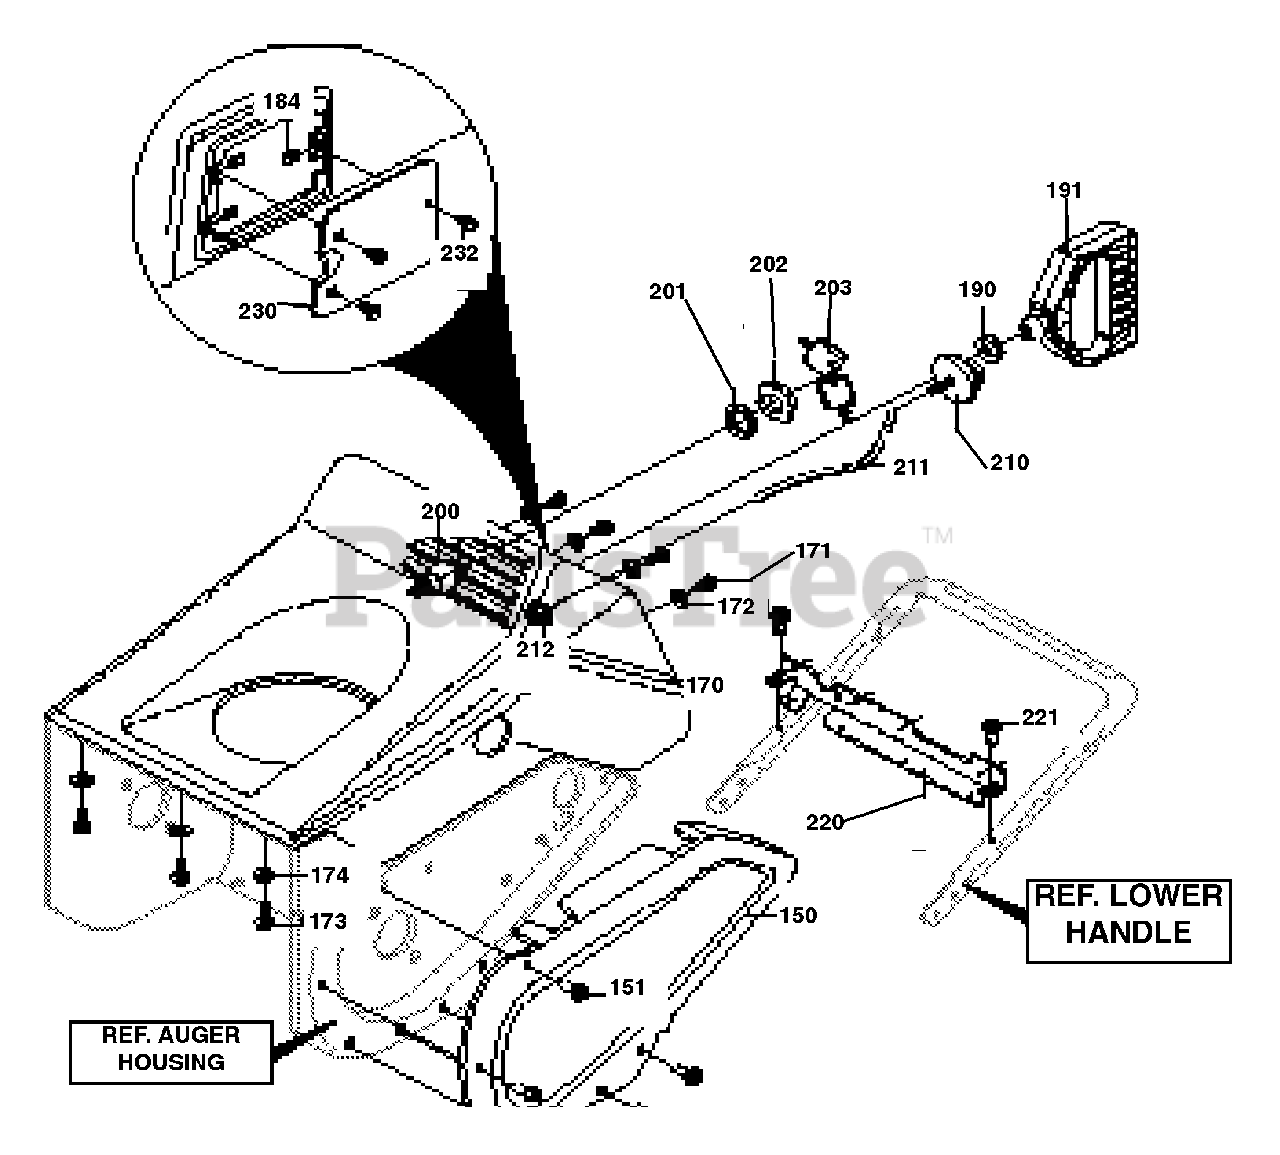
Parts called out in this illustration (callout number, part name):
150	COVER, BELT 2CY
151	SCREW, 10-24 X .38 SLHWATAP
170	COVER, TOP
171	SCREW, #10-24 X .63
172	WASHER, FLAT .203 X .56 X .04O
173	SCREW, #10-14 X .63
174	WASHER, FLAT .250 X .56 X .049
184	NUT, TINN "U" TYPE
190	GROMMET & WASHER
191	GRIP, MITTEN
200	SWITCH, IGNITION
201	WASHER, REGINTLK
202	NUT, 5/8-32
203	2 KEYS & RING
210	PRIMER, ENGINE
211	HOSE, PRIM
212	NUT, 1/4-20
220	BRACKET, SHROUD
221	SCREW, #10-24 X .63
232	SCREW #10-16 X .75
